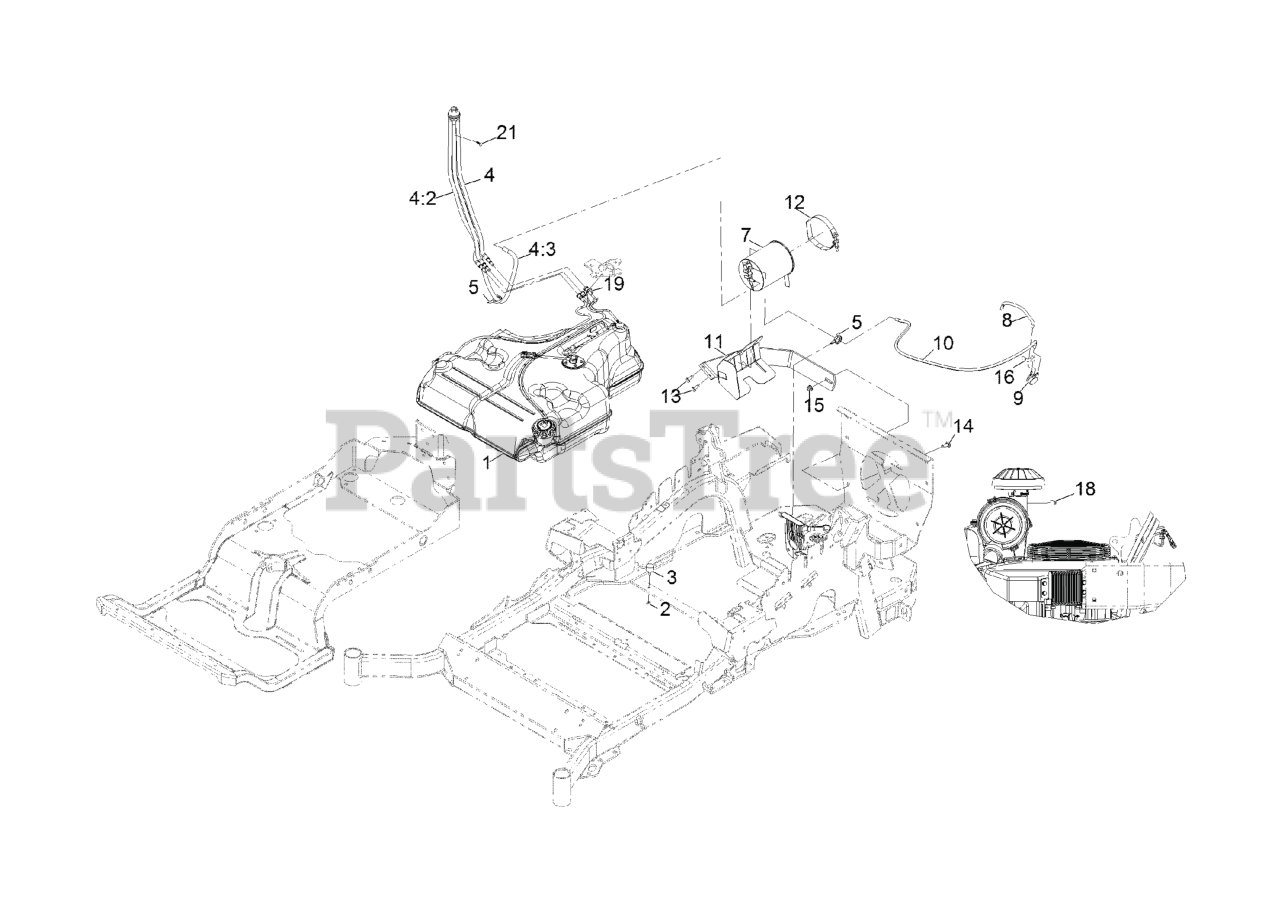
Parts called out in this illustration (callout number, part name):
1	FUEL TANK ASM
2	NUT-JAM
4	FUEL MANIFOLD VENT ASM
4:2	HOSE-FUEL
4:3	HOSE-FUEL
5	CLAMP-HOSE
7	CANISTER-CARBON, 1200CC
8	HOSE-VENT,FORMED
9	VALVE-CONTROL, VACUUM
10	HOSE,VENT,FORMED
11	MOUNT-CANISTER
12	CLAMP, T-BOLT
13	Screw-HWH 5/16-18 X 3/4 Tf
14	SCREW-CARR
15	NUT-HF, NI
16	HOSE-VENT, FORMED
18	PLUG-PORT
19	RETAINER-LINE, VAPOR
21	PLUG-PLASTIC
